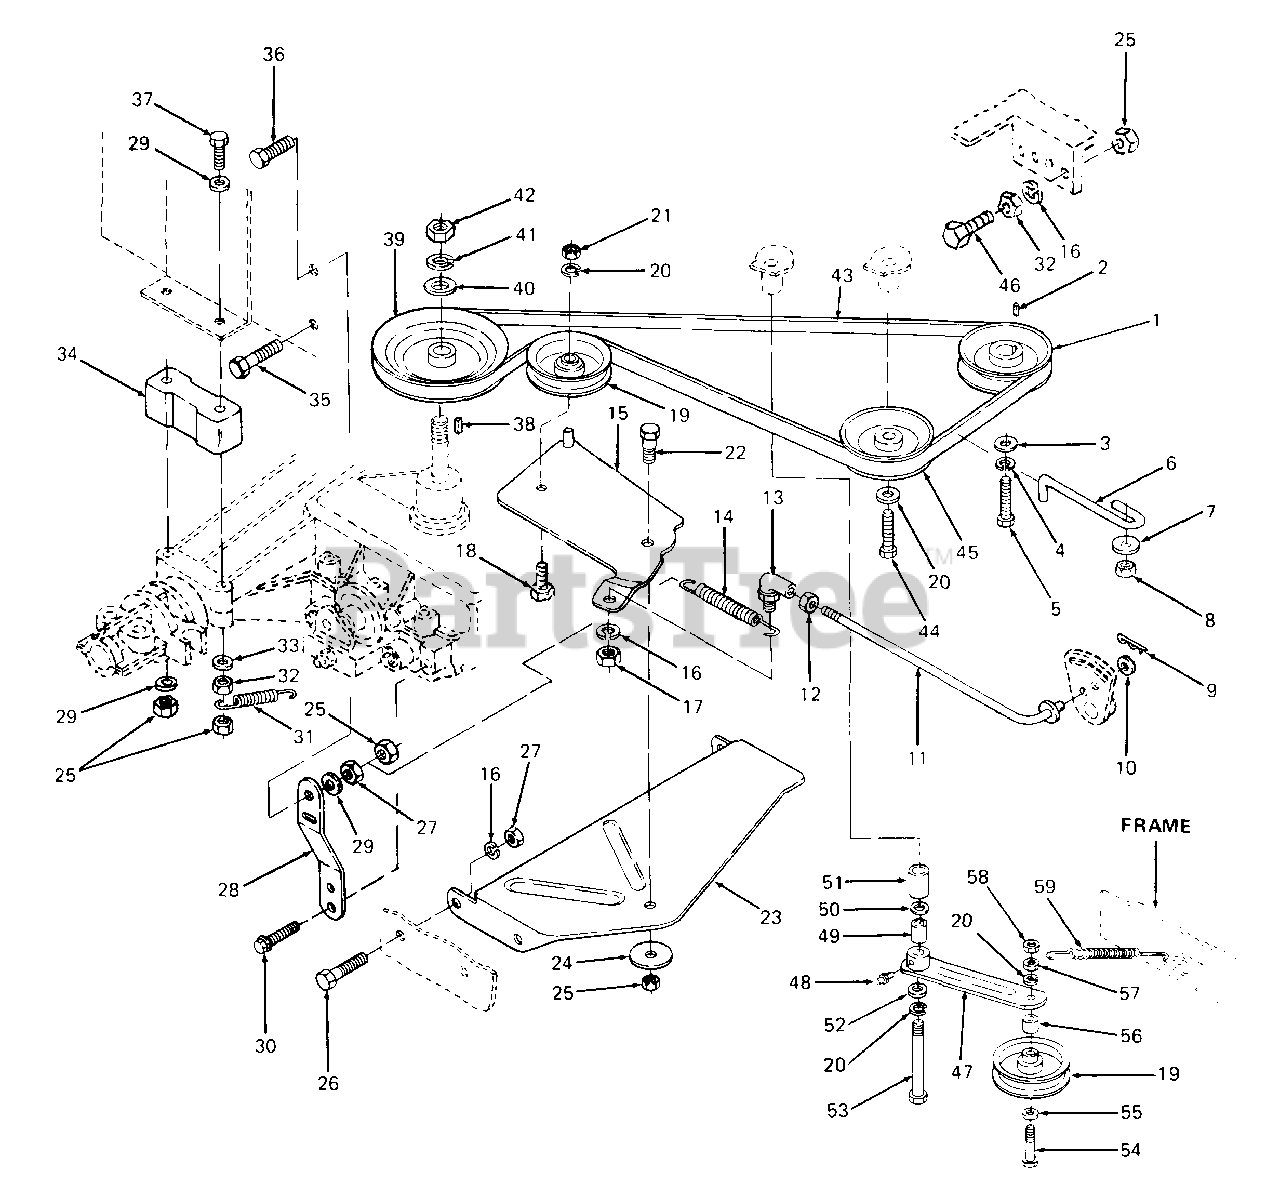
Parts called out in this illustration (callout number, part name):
1	Pulley, Engine, A Sec X 3.5 OD
2	Key, Square, 1/4 X 2.0 Lg
3	Washer, Flat, .450 X 1.25 X .172 Thk HDN
4	Washer, Lock, 7/16
5	Screw, Hex Cap, 7/16-20 X 1.5 Lg
6	Guard, Belt
7	Washer, Flat, .344 X 1.125 X .12 Thk
8	Nut, Hex Patch Lock, 5/16-24
9	Pin, Internal Cotter
10	Washer, Flat, .34 X .68 X .062 Thk
11	Rod, Idler Clutch
12	Nut, Hex Jam, 5/16-24 GR5
13	Ball Joint, 5/16-24
14	Spring, Extension
17	Nut, Hex, 5/16-24 GR5
18	Screw, Hex Cap, 3/8-16 X 2.25 Lg GR5
19	Idler, Flat, 2.75 Dia
20	Washer, Lock, 3/8
21	Nut, Hex, 3/8-16 GR5
22	Screw, Shoulder, .437 Dia X .180
23	Bracket, Clutch Mounting
24	Washer, Flat, .344 X 1.12 X .063 Thk
25	Nut, Hex Center Lock, 5/16-18 GR5
26	Screw, Hex Cap, 5/16-18 X .62 Lg
27	Nut, Hex, 5/16-18 GR5
28	Brace, Transaxle
29	Washer, Bell, .345 X .88 X .06 Thk
30	Screw, Hex Washer Hd Tapp, 5/16-18 X .75 Lg
31	Spring, Extension
32	Nut, Hex Jam, 5/16-18 GR5
33	Washer, Flat, .344 X .875 X .06 Thk
34	Spacer, Axle
35	Screw, Hex Cap, 5/16-18 X .75 Lg GR5
36	Screw, Hex Cap, 5/16-18 X 1.0 Lg GR5
37	Screw, Hex Cap, 5/16-18 X 3.75 Lg GR5
38	Key, #4 Hi-Pro, 3/32 X 5/8 Dia HDN
39	Pulley, 8.0 Dia
40	Washer, Flat, .531 X 1.00 X .027 Thk
41	Washer, Lock, 1/2
42	Nut, Hex Jam, 1/2-20
43	V-Belt, 4L X 90" Lg
44	Screw, Hex Cap, 3/8-16 X 1.25 Lg GR5
46	Screw, Shoulder
48	Fitting, Lube, 3/16 Drive
49	Spacer, .377 X .600 X .830 Lg
50	Washer, Flat, .385 X .87 X .06 Thk HDN
51	Spacer, .38 X 1.0 X 3.06 Lg
52	Washer, Flat, .406 X 1.25 X .157 Thk HDN
53	Screw, Hex Cap, 3/8-16 X 4.75 Lg GR5
54	Screw, Hex Cap, 3/8-16 X 2.75 Lg GR5
55	Washer, Flat, .385 X .620 X .063 Thk
56	Spacer, .375 X .625 X .44 Lg
57	Nut, Hex Jam, 3/8-16 GR5
58	Nut, Hex Center Lock Jam, 3/8-16
59	Spring, Extension
